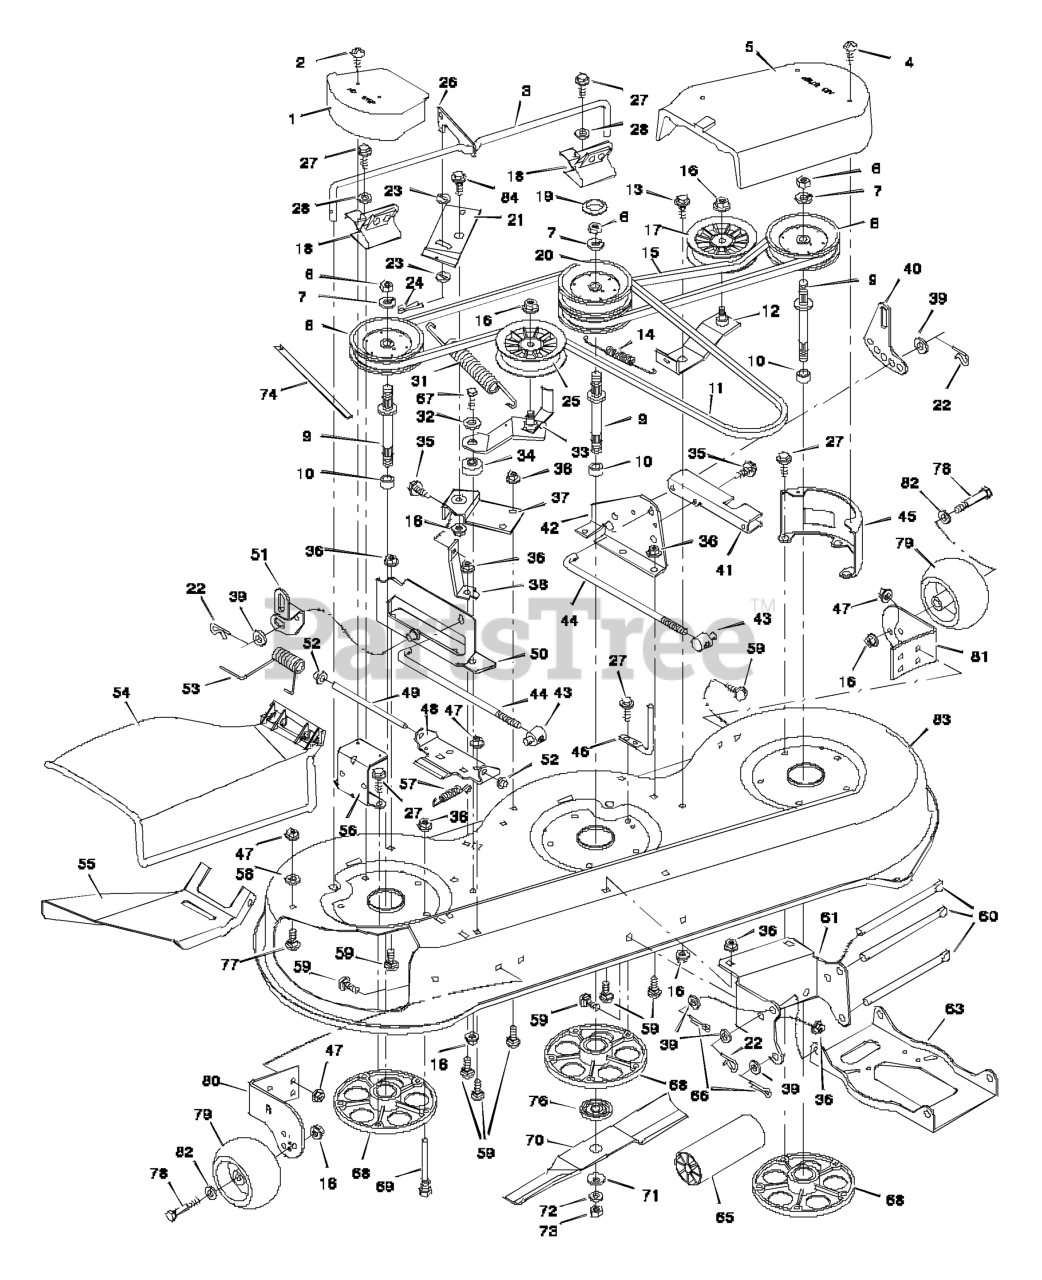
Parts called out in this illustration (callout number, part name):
1	Cover, Pulley
3	Rod, Brake
5	Cover, Left Pulley
6	Nut, Hex
7	Lockwasher
9	Jackshaft
10	Spacer, Bearing
11	Belt, Primary Mower Drive
12	Bracket, Idler
13	Bolt, Shoulder
14	Spring, Extension
15	Belt, Secondary Mower Drive
16	Locknut
17	Pulley, Idler
18	Spring Assembly, Brake
20	Pulley, Stack
21	Bracket, Pivot
22	Pin, Hair
24	Pin, Cotter
25	Pulley, Idler
26	Link, Brake
27	Screw
31	Spring, Extension
33	Bracket, Idler
34	Bushing
36	Nut, Hex
37	Support, Pivot
38	Strut, Pivot
40	Plate, Adjuster
41	Channel, Left Cover
42	Bracket Assembly, Lifter
43	NUT, Adjusting, 1/2-13
44	Rod, Adjuster
45	Bracket, Left Cover
46	Guide, Belt
47	Locknut
48	Bracket, Hinge
49	Rod, Deflector
50	Bracket Assembly, Lifter
51	Link, Suspension
52	Push- On Cap
53	Spring, Torsion
54	Deflector
55	Deflector, Inside
56	Bracket, Cover
57	Spring, Extension
59	Bolt, Carriage
60	Rod, Hanger
61	Bracket, Front Hanger
63	Hanger, Front
66	Pin, Cotter
67	Bolt, Hex
68	Housing, Mandrel
69	Guide, Belt
70	Blade (3 required)
71	Washer, Belleville
73	Nut, Hex
74	Indicator, Plastic
76	Adapter, Blade
77	Bolt, Carriage
78	BOLT, Gauge Wheel
79	Wheel, Gauge
80	Bracket, Right Gauge Wheel
81	Bracket, Left Gauge Wheel
82	Washer
83	Housing, Mower
84	Bolt, Shoulder
